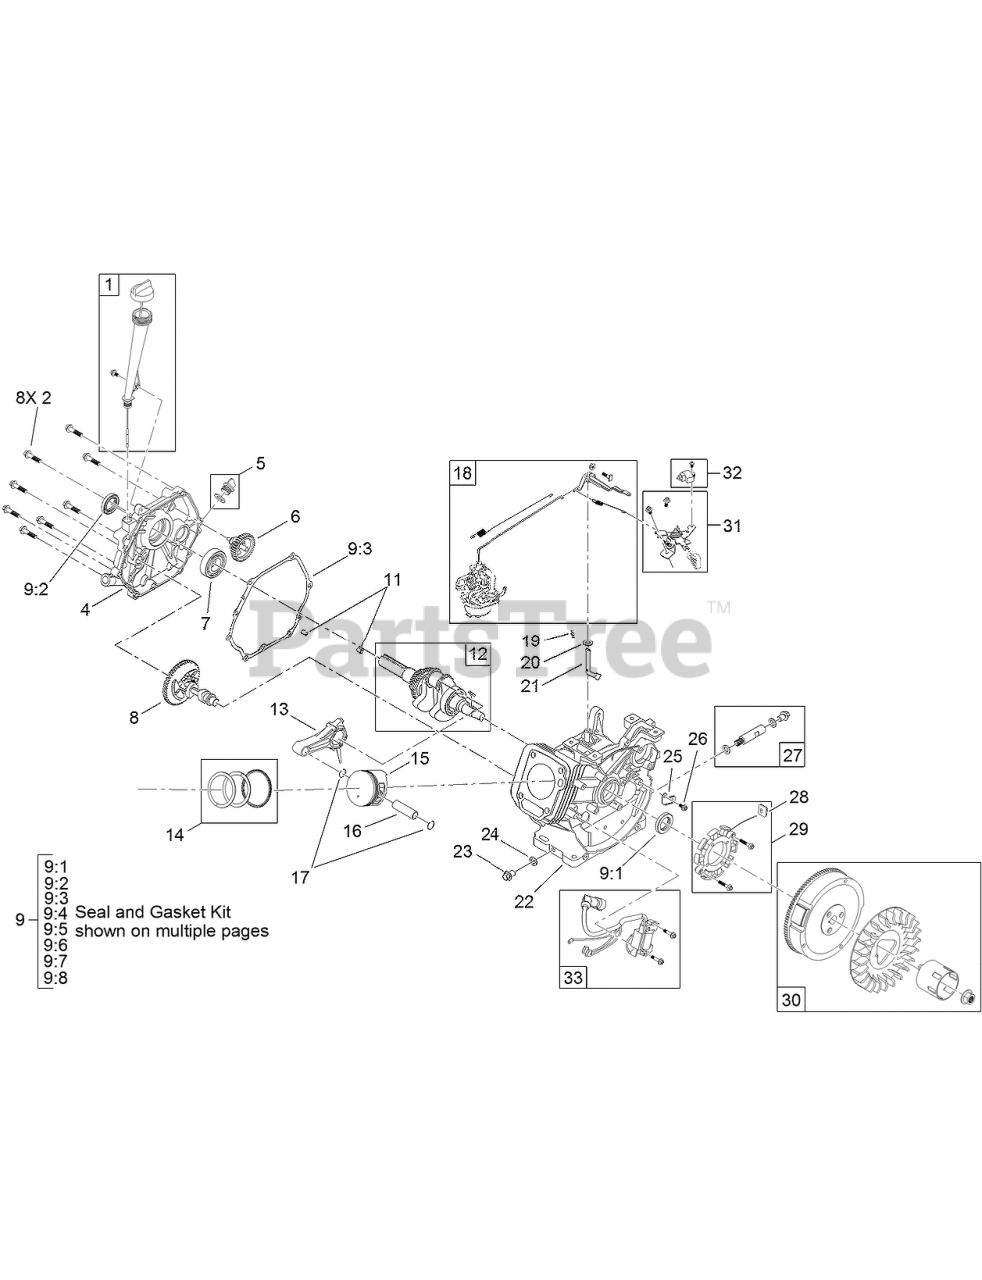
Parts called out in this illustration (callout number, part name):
1	OIL FILL KIT
2	SCREW-HHF
4	COVER-CRANKCASE
5	SUMP PLUG ASM
6	GOVERNOR GEAR ASM
7	BEARING-MAIN
8	CAMSHAFT ASM
9	SEAL AND GASKET KIT
9:1	Seal-Oil
9:2	Seal-Oil
9:3	GASKET-COVER, CRANKCASE
9:4	GASKET-HEAD, CYLINDER
9:5	GASKET-COVER, VALVE
9:6	Gasket-Exhaust
9:7	GASKET-CARBURETOR
9:8	GASKET-CARBURETOR
11	PIN-DOWEL
12	CRANKSHAFT ASM
13	CONNECTING ROD ASM
14	SET-RING, PISTON
15	PISTON
16	PIN-PISTON
17	CLIP-PIN, PISTON
18	COMPLETE GOVERNOR KIT
19	PIN-HAIR
20	WASHER-PLAIN
21	SHAFT-GOVERNOR
22	CRANKCASE
23	SCREW-HHF
24	WASHER-PLAIN
26	SCREW-HHF
27	DRAIN PLUG KIT
28	GROMMET-RUBBER
29	STATOR KIT
30	FAN AND FLYWHEEL KIT
31	THROTTLE CONTROL KIT
32	KILL SWITCH KIT
33	IGNITION MODULE KIT
